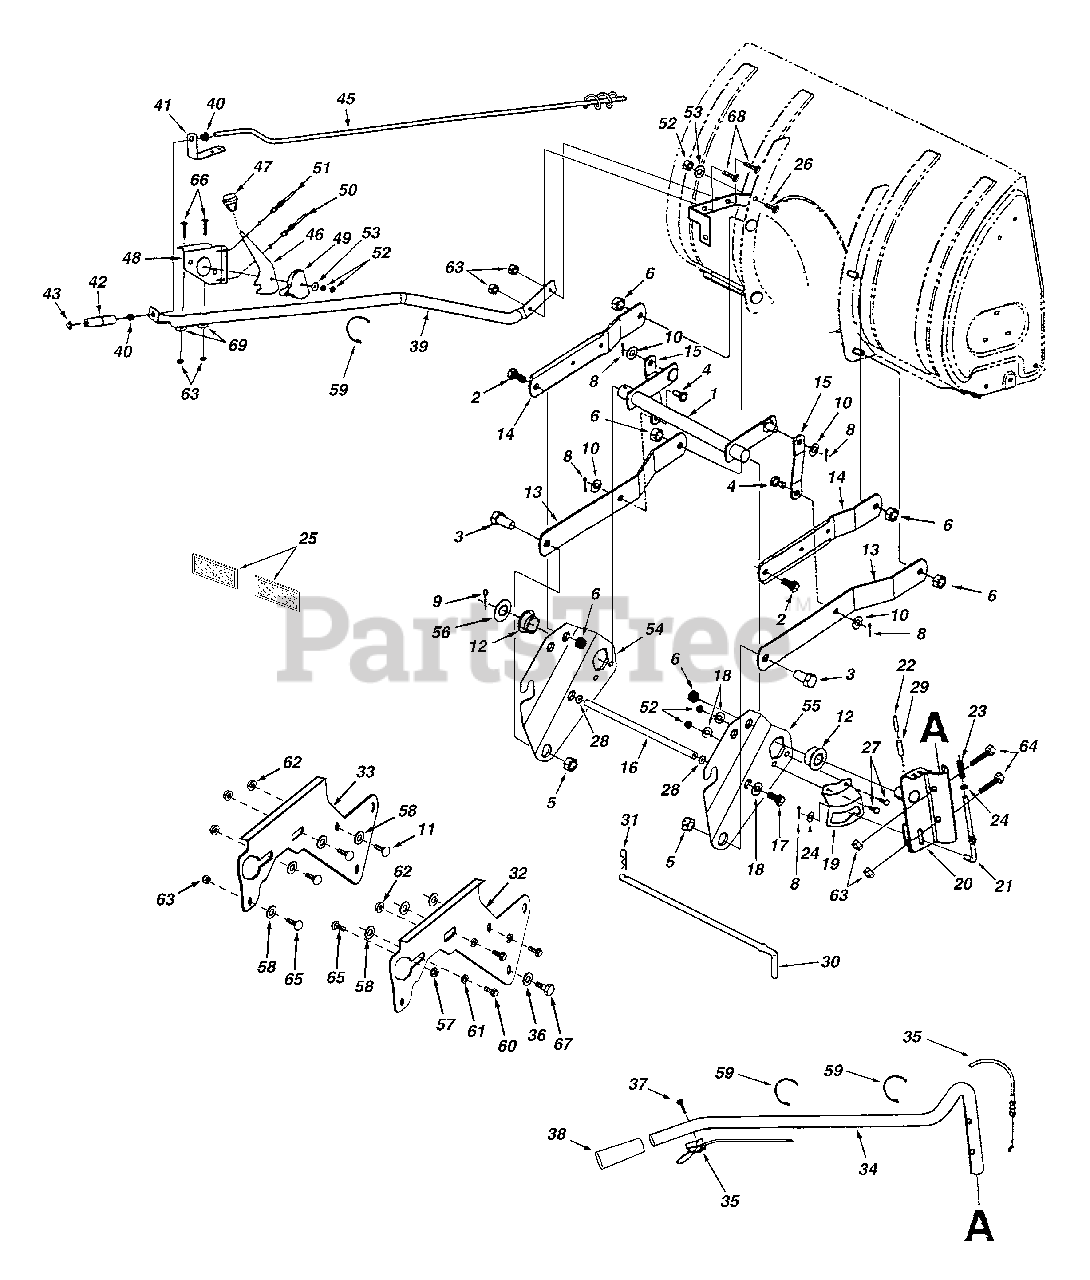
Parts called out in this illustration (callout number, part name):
1	Lift Shaft Assembly
2	Hex Bolt, 1/2-13 x 1"
3	Hex Bolt, 5/8-11 x 1-1/2"
4	Pin, Bracket Lift
5	Nut, Hex Lock 5/8-11 Thread
6	Nut, Hex Lock 1/2-13
8	Pin, Cotter 1/8" x 3/4"
9	Pin, Cotter 1/8" x 1-1/2"
10	Washer, 17/32" x 1"
11	Carriage Bolt, 3/8-16 x 1"
12	Bearing, Flange With Flats
13	Link, 15.80" Long
14	Link, 11.75" Long
15	Link, 4.88" Long
16	Rod, Spacer
17	Hex Bolt, 5/16-18 x 1" (Locking)
18	Lock Washer, 5/16"
19	Bracket, Lift
20	Assembly, Handle Lift Bracket
21	Rod, Index Lift
22	Pin, Spring 3/16" x 1-3/4"
23	Spring, Compression
24	Washer, 13/32" x 13/16"
25	Reflector, Rear
26	Carriage Bolt, 5/16-18 x 3/4"
27	Hex Bolt, 5/16-18 x 3/4"
28	Washer, 11/32 x 11/16 x 3/64
29	Pin, Spring 5/16" x 1-3/4"
30	Pin, Attachment
31	Pin, Haircotter #4 (1/8")
32	Plate, Side (R.H.)
33	Plate, Side (L.H.)
34	Tube, Lift Handle
35	Trigger and Lift Cable Assembly
36	Washer, 3/8"
37	Screw, Oval #10-24 x 1"
38	Grip, Handle
39	Tube, Crank Rod Support
40	Bushing, 3/8" Plastic
41	Bracket, Chute Crank
42	Knob, Crank
43	Palnut, 3/8"
45	Assembly, Chute Crank Rod
46	Handle, Chute Tilt
48	Assembly, Chute Tilt Bracket
49	Guide, Cable
50	Cable, Chute Control
51	Cable, Chute Control with Clip
52	Nut, Hex Lock 5/16-18
53	Washer, 5/16"
54	Plate, Mounting (L.H.)
55	Plate, Mounting (R.H.)
56	Washer, 1.59" x 1.032" x.060"
57	Nut, Whizlock, 5/16-18
58	Washer, 1/2"
59	Tie, Nylon
60	Hex Bolt, 3/8-16 x 1" Self Tap
61	Lock Washer, 3/8"
62	Nut, Flanged Lock 3/8-16
63	Nut, Nylock Hex 5/16-18
64	Hex Bolt, 5/16-18 x 1-3/4"
65	Carriage Bolt, 5/16-18 x 1"
66	Carriage Bolt, 5/16-18 x 1-3/4"
67	Bolt, Shoulder
68	Carriage Bolt, 5/16-18 x 1-1/4"
69	Washer, Bowed
